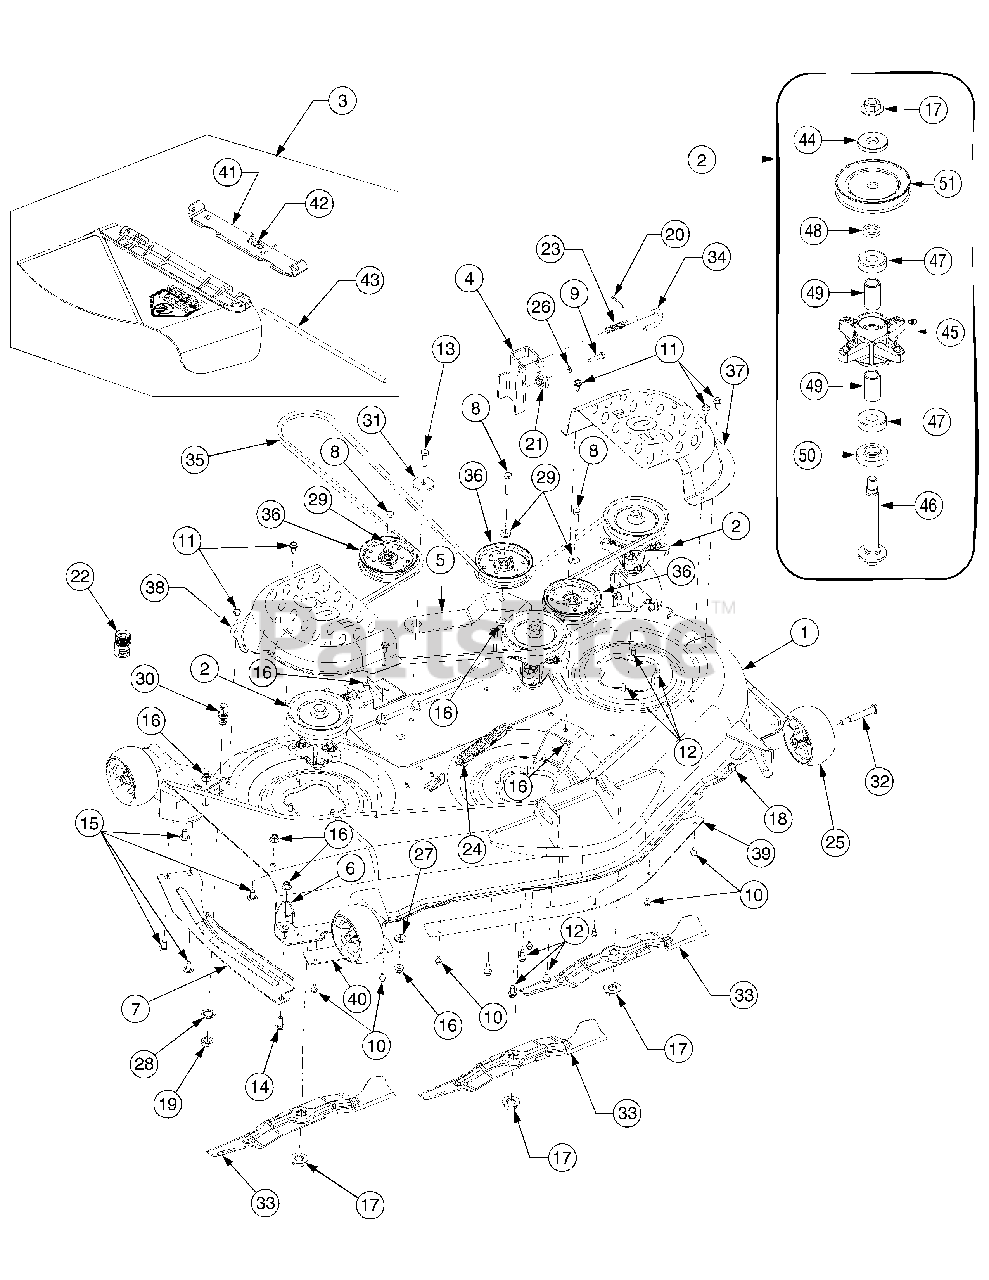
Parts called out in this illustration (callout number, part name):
1	Graphic, Danger
1	Graphic, Instruction
1	Graphic, Troy-Bilt
2	Spindle Assembly
3	Chute Assembly, Discharge
3	Graphic, Danger
8	Screw, Hex Cap, 3/8-16 x 1.75 GR5
9	Screw, Hex Cap, 5/16-18 x 1.25 GR5
10	Screw, Hex Wash. Hd. Tapp,1/4-20 x .5
11	Screw, Hex Wash. Hd. Tapp, 5/16-12 x .75
12	Screw, Hex Wash. Hd. Tapp, 5/16-18 x .75
13	Screw, Hex Cap, 3/8-16 x 1.25 GR5
14	Screw, Carriage, 3/8-16 x 1.0
15	Screw, Carriage, 3/8-16 x .75
16	Nut, Hx Insert Flange Lck, 3/6-16 GrF
17	Nut, Hex Flange, 5/8-18
18	Nut, Hex Flange Lock, 3/8-16 GRF
19	Nut, Hex, M16-1.5
20	Pin, Cotter, 1/8 x 1.25
21	Gear, Deck Adjustment
22	Adapter, Water Nozzle
23	Spring, Compression
24	Spring, Extension, .94 Dia. x 6.74
25	Wheel, Deck Ball, 5.0
26	Washer, Lock, 5/16
27	Washer, Bell, .45 x 1.0 x .062
28	Washer, Internal Tooth Lock, 5/8
29	Washer, Flat, .38 x .93 x .110 HT
30	Nozzle, Deck Wash
31	Spacer, Shoulder, .884 x .190
32	Screw, Shoulder, .5 x 2.5:3/8-16
33	Blade, 2 in 1, 17.9 Lg
34	Rod, Deck Hanger
35	Belt V, Type A Sec x 134
36	Pulley, Idler, 4.25 Dia
41	Bracket, Chute Mounting
42	Spring, Torsion
43	Pin, Hinge
44	Washer, Flat, .76 x 1.50 x .12
45	Fitting, Lube
46	Shaft, Spindle, 5.75
47	Bearing, Ball
48	Spacer, .79 x 1.25 x .175
49	Spacer, .80 x 1.10 x 1.32
50	Spacer, .79 x 1.82 x .55
51	Pulley, V Type, 5.39
